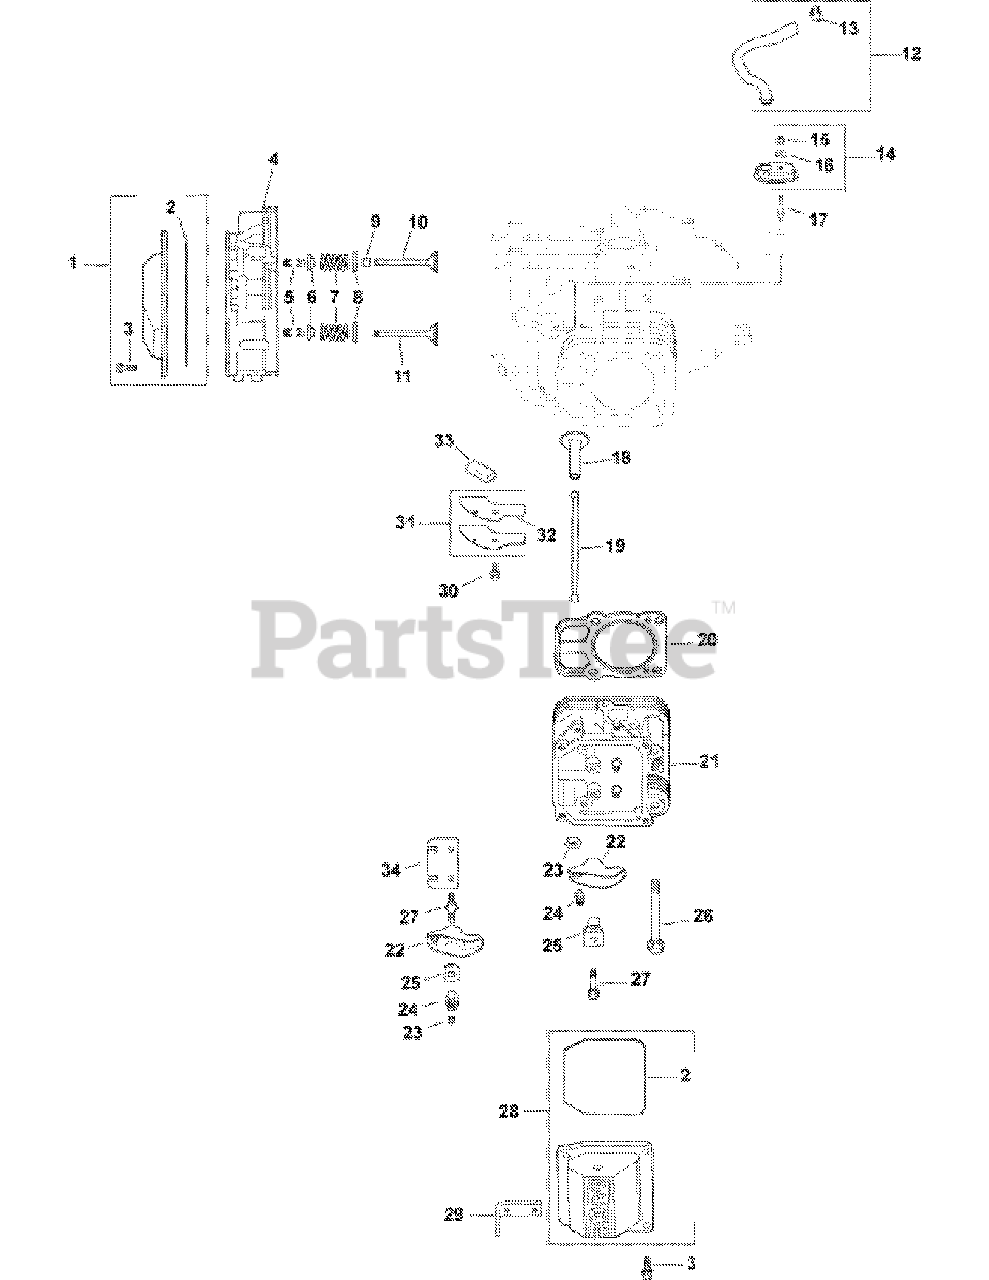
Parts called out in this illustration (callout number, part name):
1	KIT, VALVE COVER-PLAIN
2	O-RING, VALVE COVER
3	SCREW, FLG M6X1.0X30
4	KIT, #1 CYLINDER HEAD ASSEMBLY - USE 32 318 08-S
6	CAP, VALVE SPRING
8	RETAINER, SPRING
9	SEAL, VALVE STEM
10	VALVE, INTAKE (STD)
11	VALVE, EXHAUST (STD)
12	KIT, BREATHER HOSE
13	CLAMP, SPRING HOSE 1/2"
14	KIT, BREATHER HOUSING
15	NUT, LOCK M5X.8
17	STUD, BREATHER COVER
18	KIT,TAPPET - USE 32 019 02-S
19	ROD, PUSH
20	KIT, CYLINDER HEAD GASKET
21	KIT, #2 CYLINDER HEAD ASSY - USE 32 318 10-S
22	ARM, ROCKER
23	NUT, M10X0.75
23	NUT, HEX
24	SCREW, SET
25	PIVOT, ROCKER ARM
26	SCREW, FLG M10X1.5X90
27	SCREW, FLG M6X1.0X45
27	STUD, ROCKER
28	KIT, BREATHER VALVE COVER
29	STRAP, LIFTING
30	SCREW, FLG THD FRM M6X1.0X16
31	KIT, BREATHER COVER
32	GASKET, BREATHER COVER - DISC.
33	FILTER, BREATHER
34	PLATE, GUIDE
